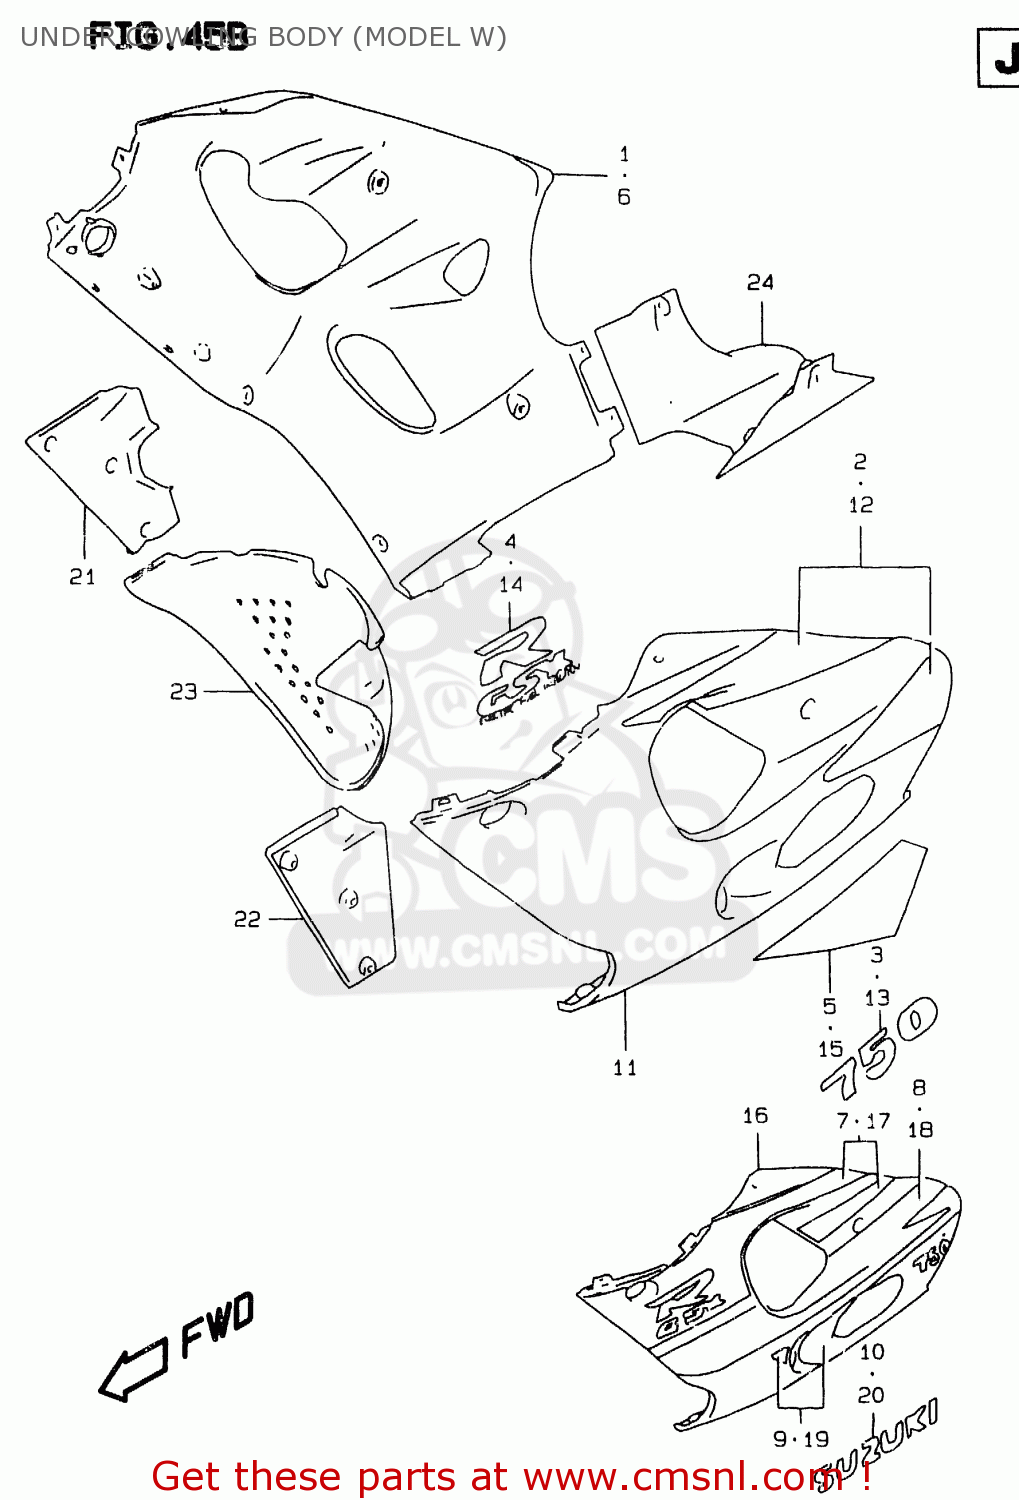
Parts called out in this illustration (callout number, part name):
1	COWLING,UNDER,
2	TAPE SET,COWL UNDER,R
3	EMBLEM,COWLING,UNDER
4	EMBLEM,COWLING
5	TAPE,COWL UNDER,R
6	COWLING ASSEMBLY,UNDER,RIGHT
7	TAPE SET,COWL UNDER UPR,R
8	EMBLEM,COWLING UNDER
9	TAPE SET,COWL UNDER(750),R
10	EMBLEM,SUZUKI
11	COWLING,UNDER,
12	TAPE SET,COWL UNDER,L
13	EMBLEM,COWLING,UNDER
14	EMBLEM,COWLING
15	TAPE,COWL UNDER,L
16	COWLING ASSY,UNDER,L
17	TAPE SET,COWLING,UNDER,UPPER
18	TAPE SET,COWL UNDER,L
19	TAPE SET,COWL UNDER(750),L
20	EMBLEM,SUZUKI
21	COWLING,UNDER INNER,R
22	COWLING,UNDER INNER,L
23	COWLING,UNDER,CENTER
24	COWLING ASSEMBLY,UNDER,REAR
